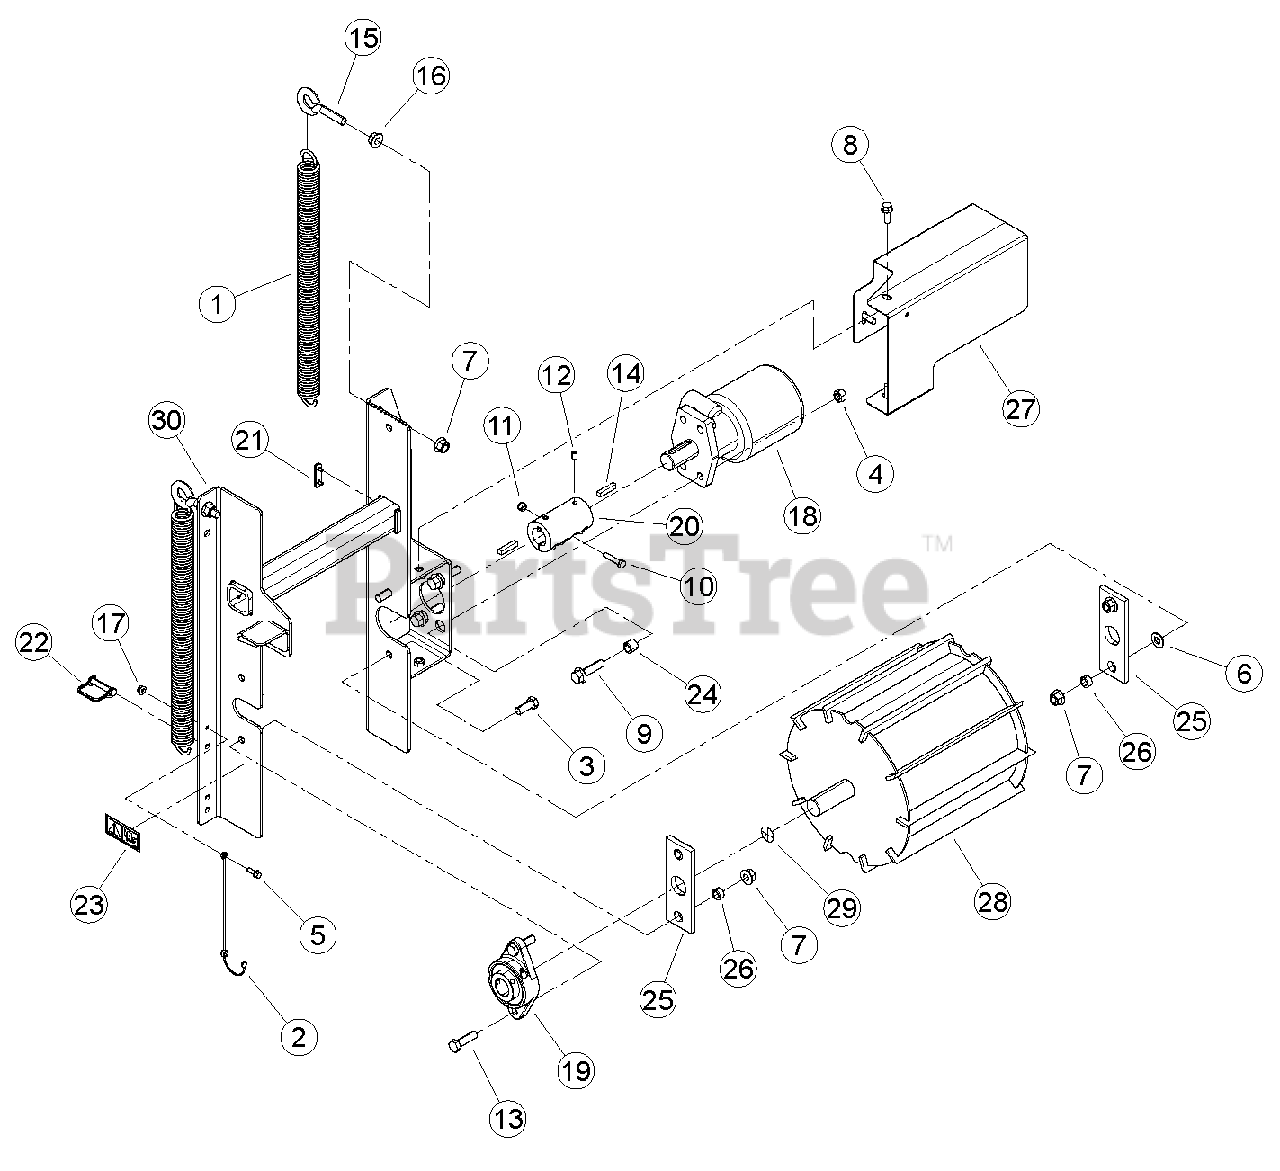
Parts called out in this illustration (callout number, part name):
1	SPRING, EXTENSION
2	LANYARD, NYLON
3	BOLT, 1/2 X 1-1/4" GR5 HHCS NC ZP
4	NUT, 1/2-13 GR5 CENTERLOCK GRB
5	BOLT, 1/4-20 X 3/4 HWH GR5 CZP
6	WASHER, 1/2 SAE FLAT
7	NUT, 1/2-13 NYLOCK FLANGE
8	BOLT, 3/8 X 1 FLANGE NC
9	BOLT, 1/2-13 X 2 HWH GR5 CZP
10	BOLT, 5/16 X 1-1/2 GR5 HEX CPS ZP
11	NUT, 5/16-18 NE NYLOCK
12	SCREW, 3/8 X 1/2 CUP PT SKT SET
13	BOLT, 1/2-13 X 1-3/4 GR5 HCPS
14	KEY, 5/16 X 1-1/2 SQUARE
15	EYEBOLT, 1/2-13 X 2
16	NUT, 1/2 SPIRAL LOCK NC ZP
17	NUT, 1/4-20 NYLOCK FLANGE
18	MOTOR, 45 CU IN HYDRAULIC
19	BEARING, 1-1/4" DIA 2 BOLT FLANGE
20	COUPLER, 1-1/4 SHAFT
21	WEAR PAD, STD. SPRING HD FRONT
22	PIN, 3/8 X 1-1/2 LYNCH
23	DECAL, CRUSHING ISO
24	SPACER, 0.75 X 0.620
25	BEARING, SLIDE
26	SPACER, .75 OD X .5 ID X .37
27	WELDMENT, MOTOR COVER
28	ASSEMBLY, 6" FEED ROLLER
29	DECAL, ROTATING SHAFT
30	WELDMENT, ROLLER SLIDE
